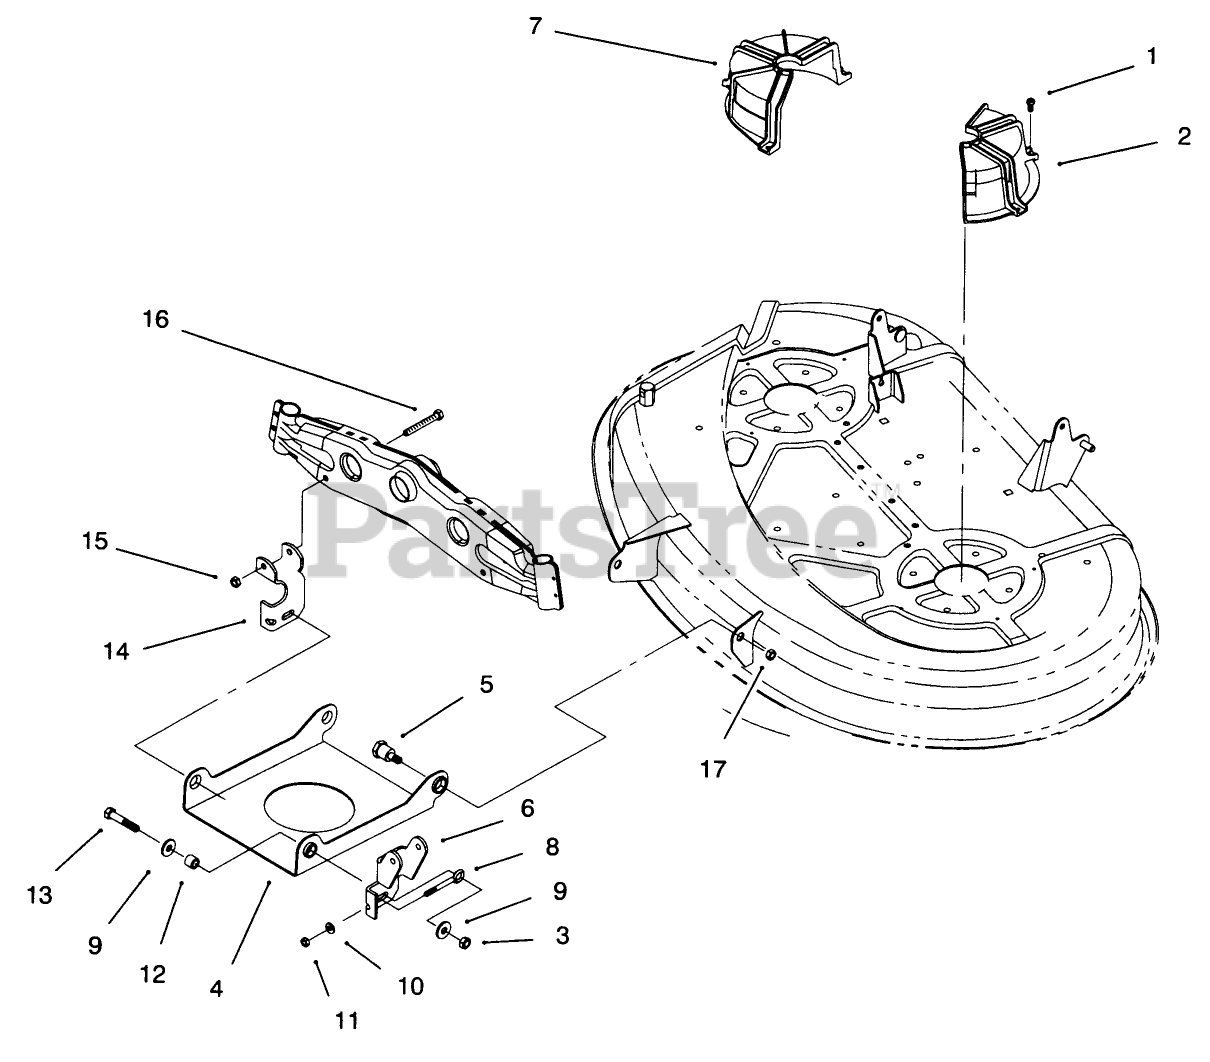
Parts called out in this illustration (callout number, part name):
1	SCREW-HWHTF
2	GUIDE-BELT, LH
3	NUT-LOCK, NI
4	PAN-DECK SUSPENSION, FRONT
6	BRACKET-SUSPENSION, LH
7	GUIDE-BELT, RH
8	SCREW-ADJUSTING
9	WASHER-HARDENED
10	WASHER-FLAT
11	NUT-LOCK, NI
12	SPACER
13	SCREW-HH
14	BRACKET-SUSPENSION, RH
15	NUT-LOCK, NI
16	SCREW-HH
17	NUT-LOCK, NI
